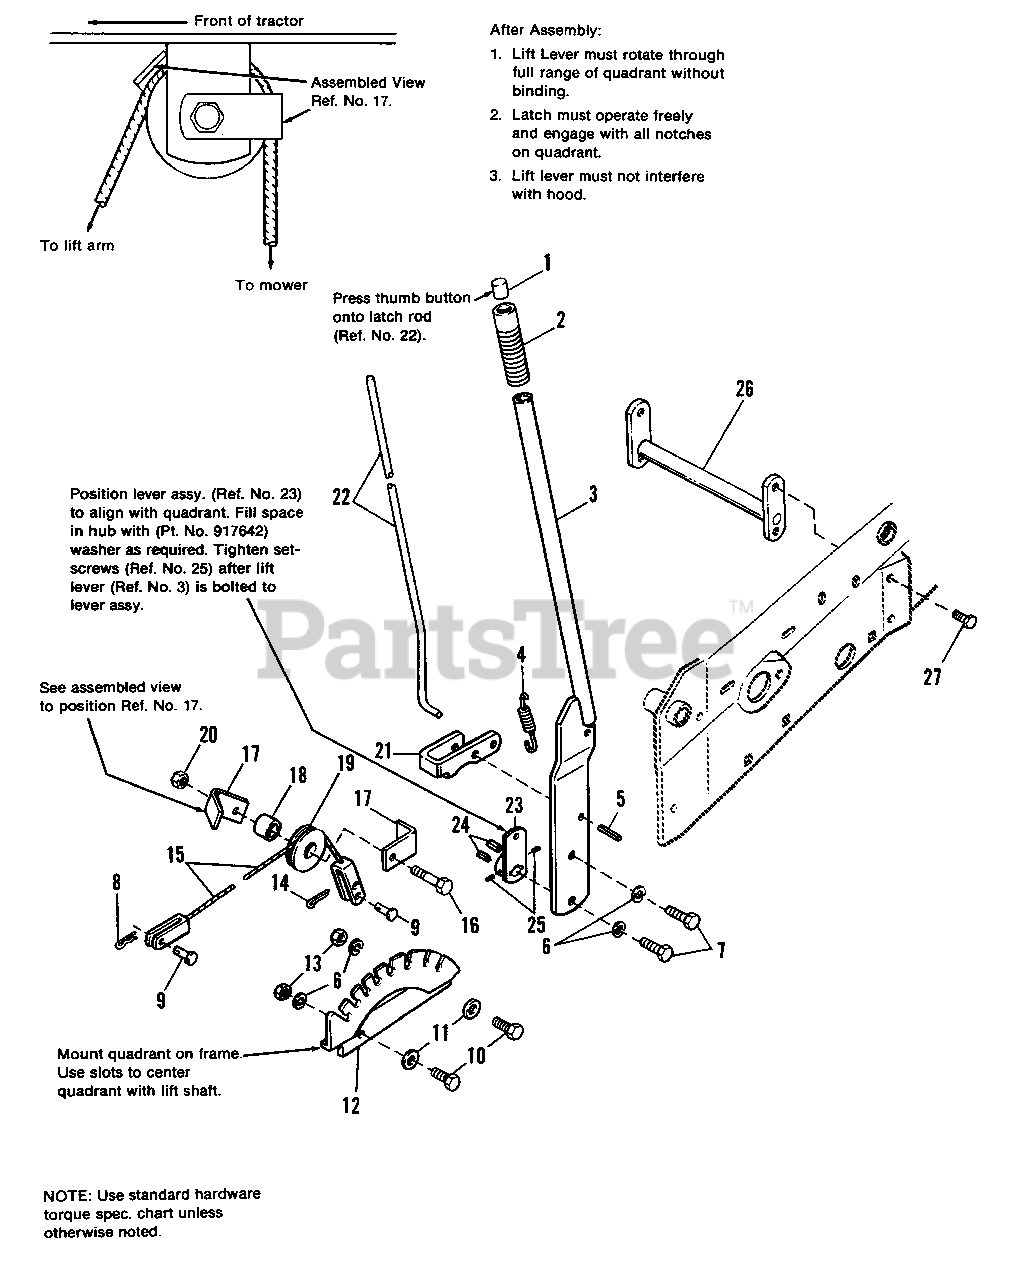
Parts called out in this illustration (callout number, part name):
2	GRIP
3	LEVER ASSY., Lift
5	PIN, Spring, 3/8 x 1-1/4
6	LOCKWASHER, 3/8
7	CAPSCREW, Hex Hd., 3/8-16 x 1
8	CLIP, Spring
10	CAPSCREW, Hex Hd., 3/8-16 x 7/8
11	WASHER, Plain, 5/16
13	NUT, Hex, Full, 3/8-16
14	PIN, Cotter, 3/32 x 1
15	CABLE ASSY., Lift
16	SCREW, Special
17	GUARD, Cable
20	LOCKNUT, Hex, Jam, 3/8-16
21	LATCH, Lift Lever
22	ROD, Latch
23	LEVER ASSY., Lift
25	SETSCREW, 5/16-18 x 1/4
26	SUPPORT ASSY.
27	SCREW, Self-Tapping, 3/8 x 3/4
